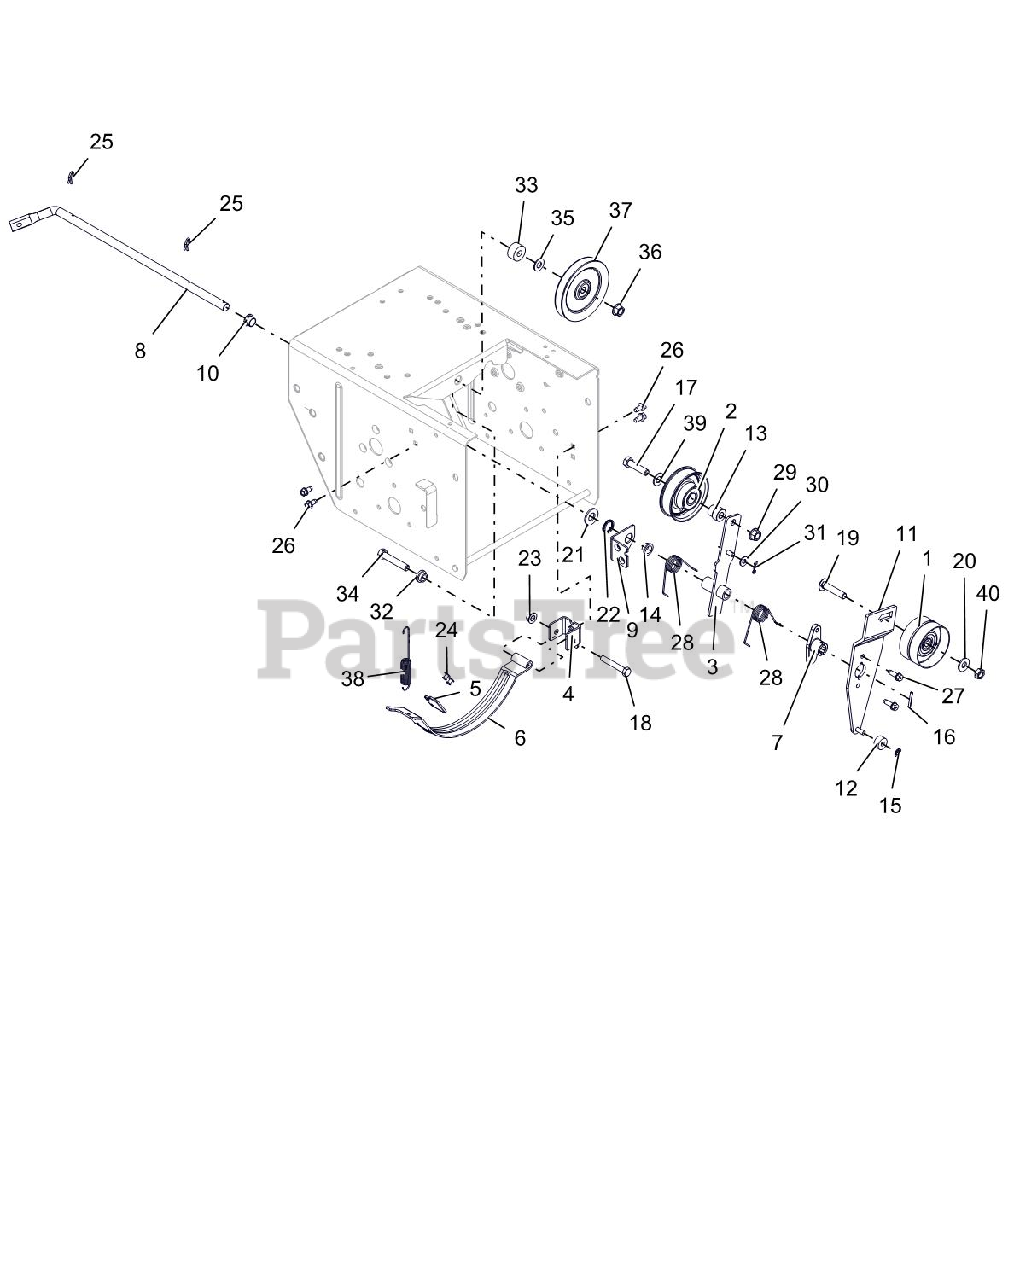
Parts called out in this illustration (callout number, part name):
1	IDLER, FLAT-2.75 OD X .375 ID
2	IDLER, FLAT - 3.05" X .75"
3	ARM, TRACTION CLUTCH
4	PIVOT, BRAKE
5	PAD, BRAKE
6	ARM, BRAKE-ATTACHMENT
7	HUB, BRAKE ARM
8	ARM, ATTACHMENT
9	BRACKET, SUPPORT
10	BUSHING, POLYLINER-.50 SPLIT
11	ARM, IDLER-ATTACHMENT
12	BSHG,SLV .265 X .625 X .375
13	BSHG-FLG .378X.442X.826X.81
14	BSHG,FLANGE .500X.625X.270X.75
15	RG-RTNG-EXT .250X.010
16	PIN-ROLL .125X1.00
17	@BLT-HEX .38-16X1.50 GR5 YWZC
18	@BLT-HEX .31-18X2.00 GR5 YWZC
19	@BLT-RHDSSQNK .38-16X1.75 G5YZ
20	@WSHR-FL-STL.38X.875X.083 YWZC
21	@WSHR-FL-STL.531X1.06X.095YWZC
22	WAVE SPRING .600X.875X.25FH
23	@NUT-LK-TOP-FLG .31-18 YWZC
24	RVT-POP .187 YZ
25	CLIP, SPRING
26	SCR-TAP .25-20X.50 HWH TR YWZ
27	SCR-TAP-PM .25-20X.75 TR YWZ
28	SG-TORS .067X.88
29	@NUT-LK-TOP-FLG .38-16 YWZC
30	@WSHR-FL-STL.281X.62X.065 YWZC
31	PIN-HAIR INT .06X.18X.77
32	BSHG, FLANGE .391X.56X.313X.75
33	BSHG,POCKET .391X.570X1.0X.450
34	@BLT-HEX .38-16X2.00 GR5 YWZC
35	@WSHR-FL-STL.406X.812X.065 YWZ
36	@NUT-LK-TOP-FLG .38-16 YWZC
37	SHV, .38"ID X 4.00"OD V-IDLER
38	SG-TENS .056X.60X4.40
39	@WSHR-FL-STL.406X.812X.065 YWZ
40	@NUT-LK-CTR-JAM .375-16 YWZC
